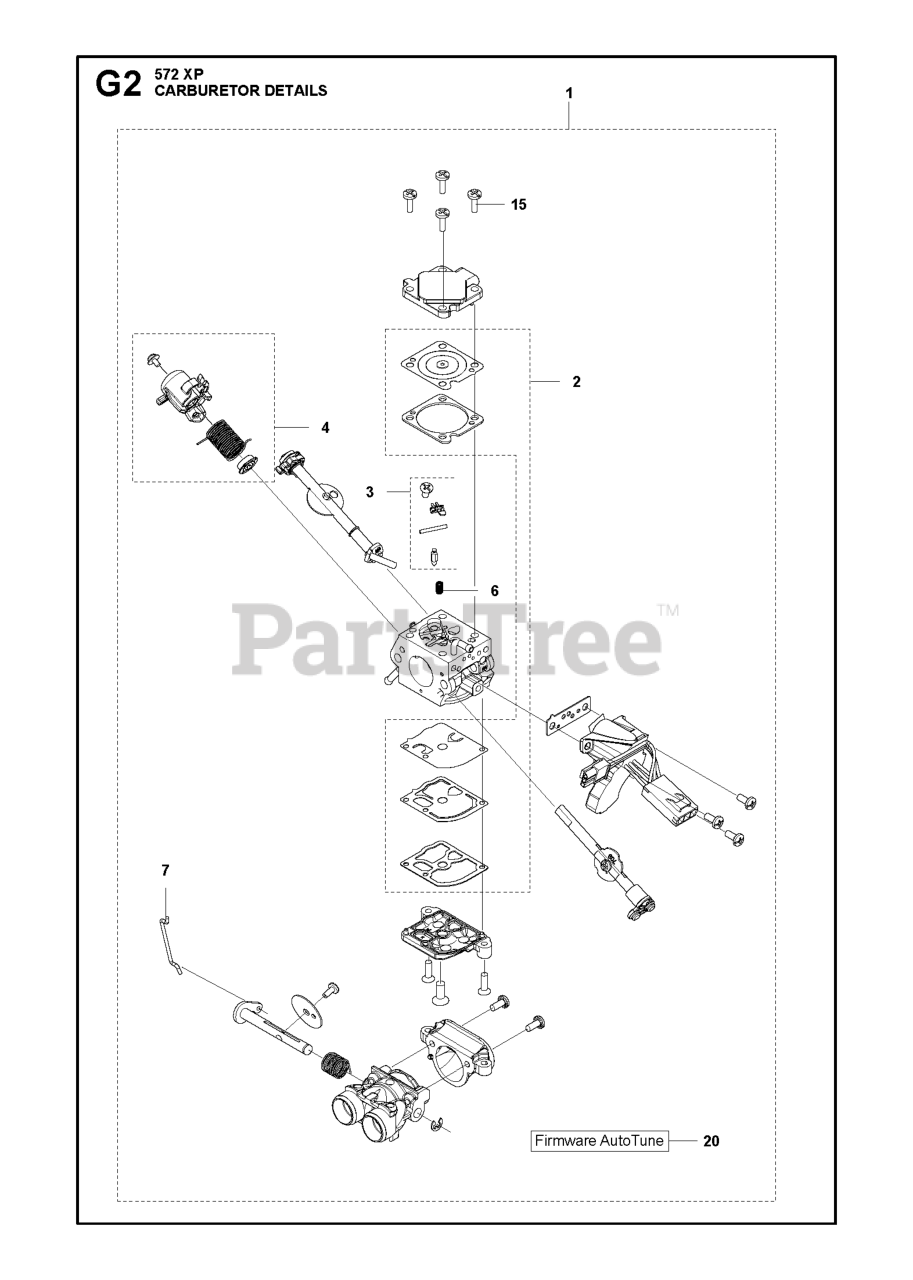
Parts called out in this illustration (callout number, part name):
1	CARBURETTOR KIT 572XP
2	KIT GASKET AND DIAPHRAM
3	CARBURETTOR METERING KIT
4	CARBURETTOR THROTTLE LEVER KIT
